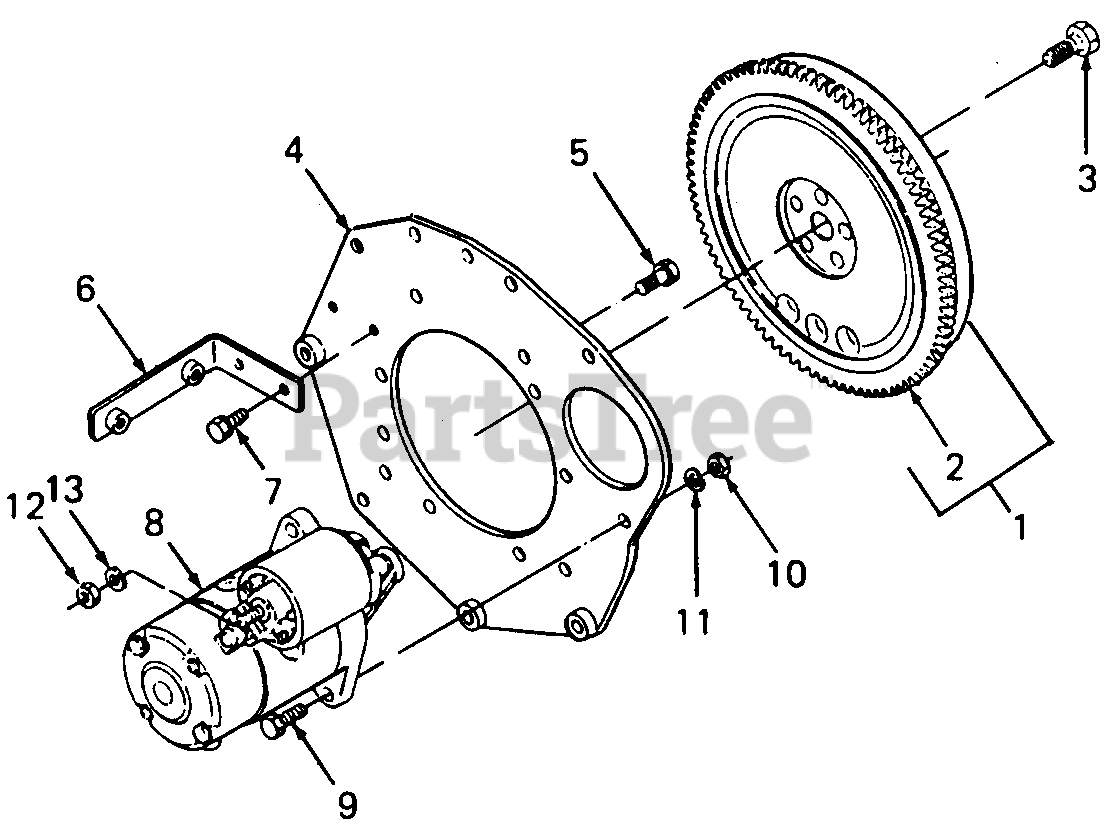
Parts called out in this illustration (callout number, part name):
3	Bolt, Flywheel
4	Plate, Rear End
6	Support, Cover
8	Starter Assy
11	Washer, Spring
13	Washer, Spring
